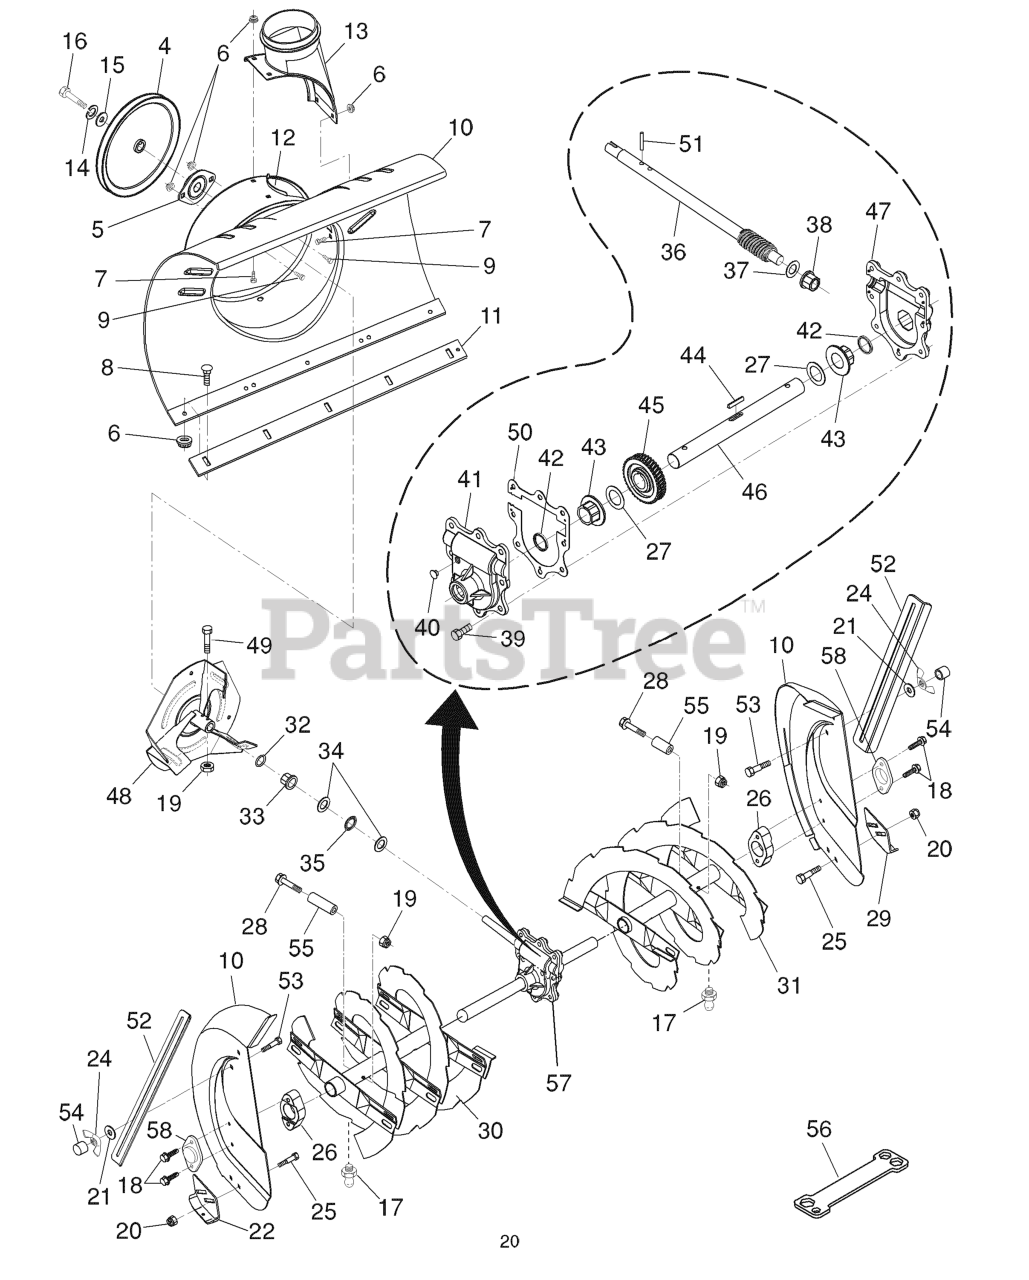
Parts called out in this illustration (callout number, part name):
4	PULLEY, IMPELLER
5	BEARING FLANGE
6	NUT.FLANGE.5/16
7	BOLT.CARRIAGE.5/16-18X
8	BOLT
9	BOLT, HEX HEAD 5/16-18
10	HOUSING, AUGER
11	BAR, SCRAPER
12	BRACKET, CORNER DISCHARGE
13	BASE DISCHARGE CHUTE
14	WASHER.LOCK.HVY.HLCL.SPR.5/16
15	WASHER, FLAT
16	CAPSCREW.HX.HD.5/16-18X1.00.NY
17	GREASE FITTING
18	SCREW, HEX HD 5/16X1
19	LOCKNUT.NYLOC.1/4-20
20	NUT.FLANGE.5/16
21	WASHER.12021.438X.75X.06.PLS
22	SKID PLATE
24	NUT WING PM
25	BOLT
26	BEARING RETAINER, PLASTIC
27	WASHER TRUST 1"
28	BOLT, SHEAR
30	AUGER ASSY-RH
31	AUGER ASSY-LH
33	BUSHING, FLANGE 3/4
34	WASHER, THRUST 3/4
35	BEARING TRUST 3/4 NTA-1220
36	SHAFT, IMPELLER
37	WASHER, THRUST 5/8
38	FLANGE BUSHING-5/8
39	HEX SCREW-5/16 X 3/4
40	CASE PLUG
41	GEARBOX HOUSING-RH
42	OIL SEAL
43	FLANGE BUSHING-1"
44	KEY, SQUARE 1/4 X .875
45	WORM GEAR
46	AUGER SHAFT
47	HOUSING.GEARBOX.LH(SERVICE)
48	IMPELLER ASSY
49	SCREW.HEX.HD1/4-20X
50	GEARBOX GASKET
51	PIN, ROLL 3/16 X 1-1/8
52	DRIFT CUTTER BAR
53	BOLT
54	STOP.11261.PLASTIC.30X50L.RED
55	SPACER.3943.SLEEVE.250X.47
56	RP WRENCH, SNOWTHROWER
57	GEARBOX.ASSEMBLY.AUGER
58	BEARING.BALL.AUGER.SHAFT
